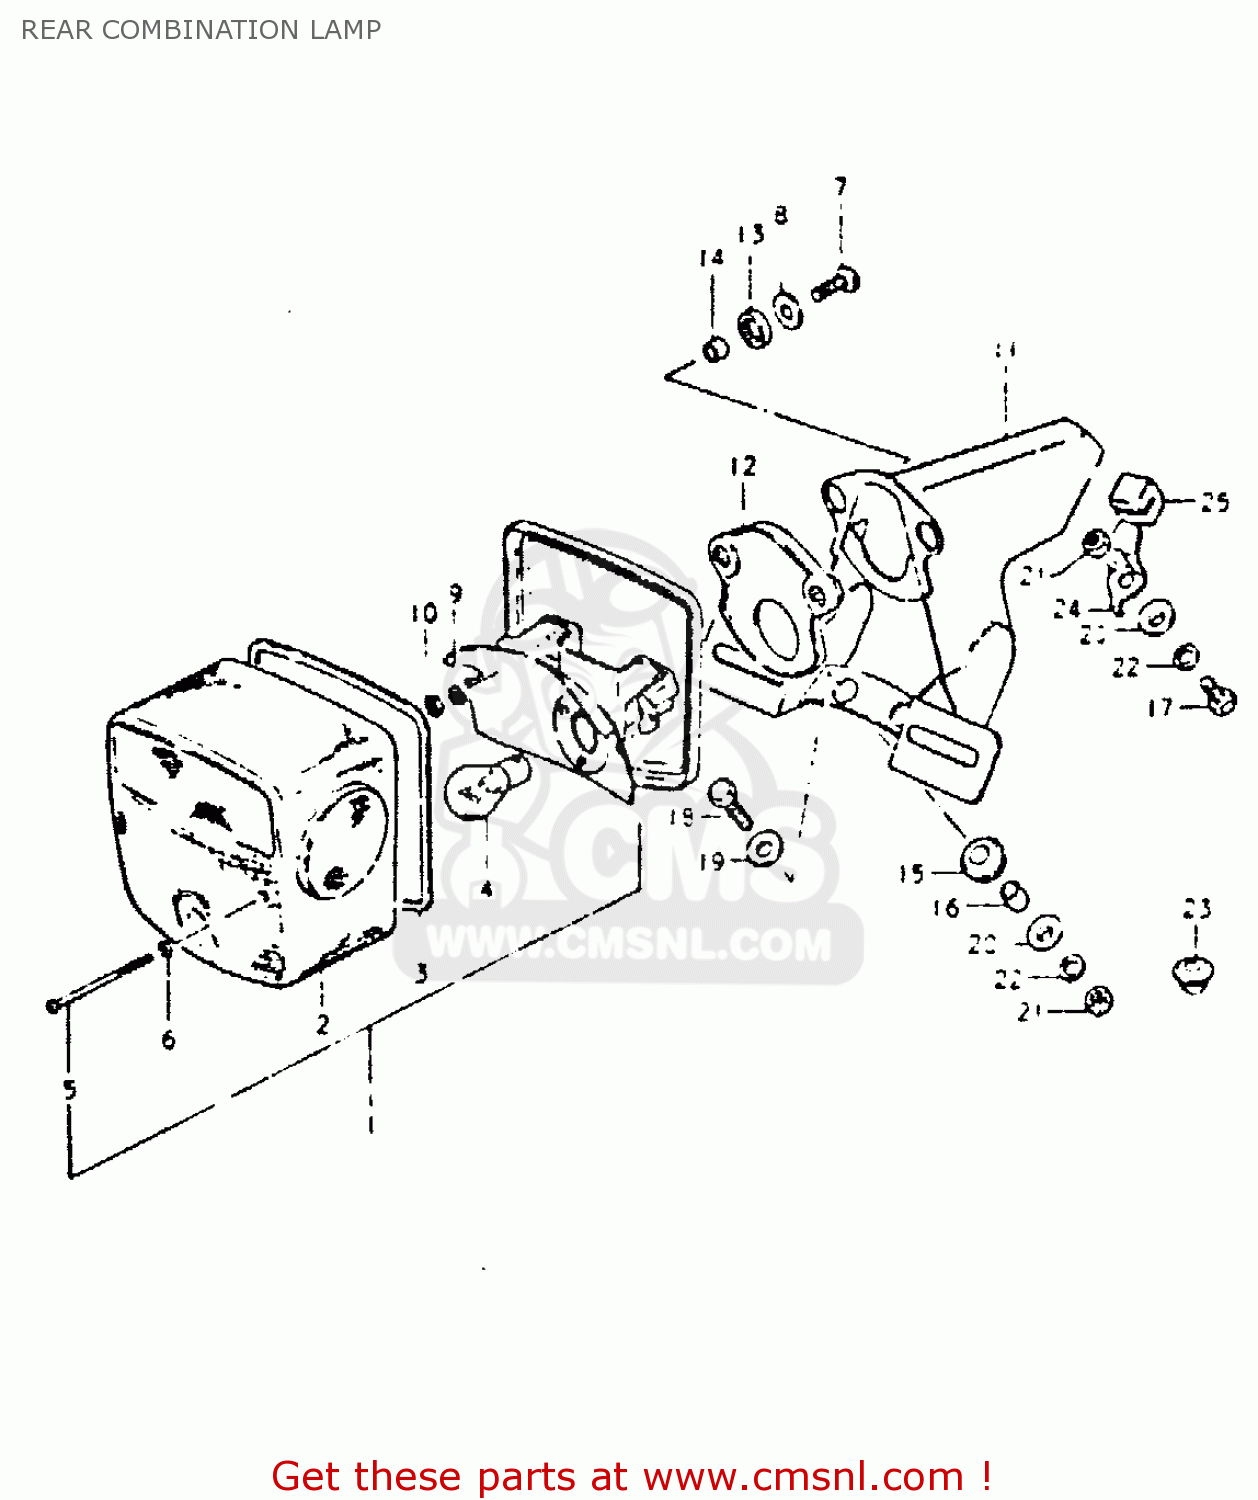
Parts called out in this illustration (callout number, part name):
1	LAMP UNIT, TAIL
2	LENS
3	GASKET (NAS)
4	BULB(6V32/3CP,STANLEY)
5	SCREW (4X55)
6	GASKET (NAS)
7	SCREW
8	WASHER,REAR COMBINATION LAMP
9	NUT
10	LOCK WASHER
11	BRACKET SET
12	CUSHION
13	CUSHION
14	SPACER,REAR COMBINATION LAMP
15	CUSHION,REAR COMBINATION LAMP
16	SPACER
17	BOLT
18	BOLT
19	WASHER (6.5X20X1.2)
20	WASHER
21	NUT
22	WASHER
23	GROMMET
24	PLATE,TAIL LAMP
25	CUSHION,REAR COMBINATION LAMP
